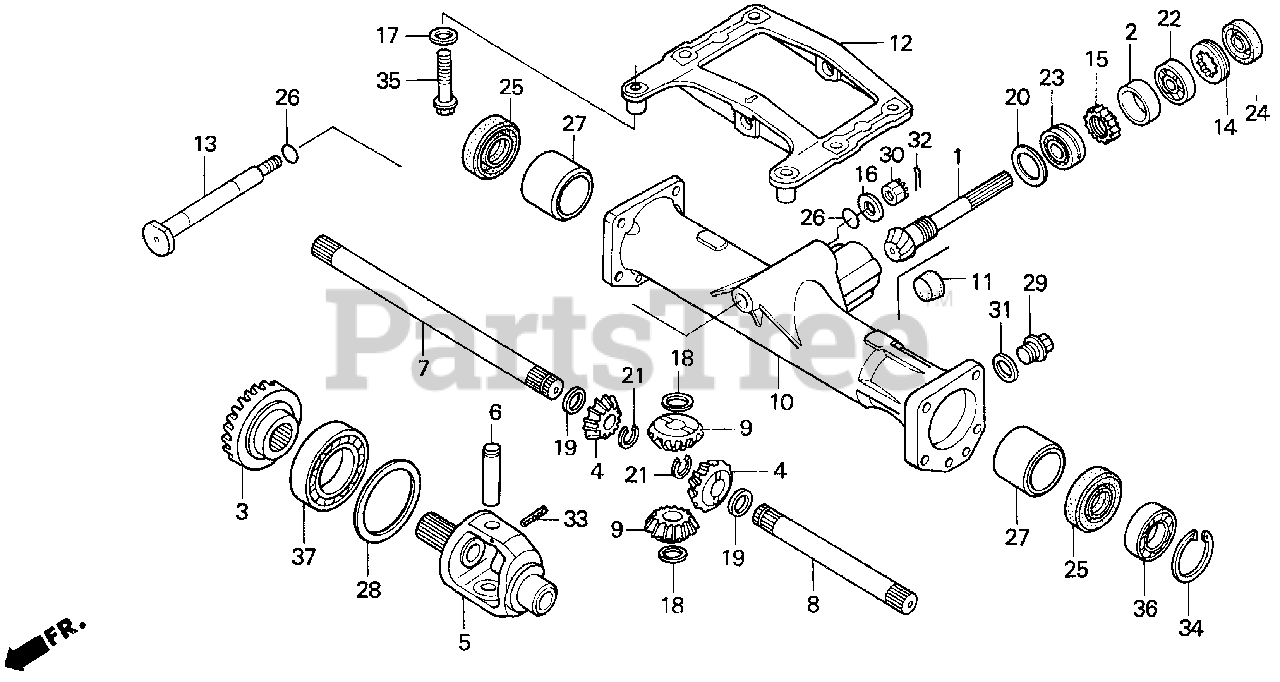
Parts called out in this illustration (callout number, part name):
1	SHAFT, FR. DIFFERENTIAL INPUT
2	COLLAR, FR. DIFFERENTIAL INPUT SHAFT
3	GEAR, FR. DIFFERENTIAL DRIVEN
4	GEAR, FR. DIFFERENTIAL SIDE
5	CASE, FR. DIFFERENTIAL GEAR
6	SHAFT, DIFFERENTIAL PINION
7	SHAFT, R. FR. DRIVE
8	SHAFT, L. FR. DRIVE
9	PINION, DIFFERENTIAL (14T)
10	TUBE, FR. AXLE
12	BRACKET, FR. AXLE
13	PIN, PIVOT CENTER
14	NUT, LOCK (55MM)
15	NUT, LOCK (25MM)
16	WASHER, PIVOT BOLT (NOT AVAILABLE)
17	WASHER, PLAIN (12MM)
18	WASHER A, DIFFERENTIAL PINION (16.2X30X0.7)
18	WASHER B, DIFFERENTIAL PINION (16.2X30X0.8)
18	WASHER C, DIFFERENTIAL PINION (16.2X30X0.9)
18	WASHER D, DIFFERENTIAL PINION (16.2X30X1.0)
19	WASHER, DIFFERENTIAL GEAR
20	SHIM, PINION (45.5X51.5X1.35) (A)
20	SHIM, PINION (45.5X51.5X1.4) (B)
20	SHIM, PINION (45.5X51.5X1.45) (C)
20	SHIM, PINION (45.5X51.5X1.5) (D)
20	SHIM, PINION (45.5X51.5X1.55) (E)
20	SHIM, PINION (45.5X51.5X1.6) (F)
20	SHIM, PINION (45.5X51.5X1.65) (G)
20	SHIM, PINION (45.5X51.5X1.7) (H)
20	SHIM, PINION (45.5X51.5X1.75) (I)
20	SHIM, PINION (45.5X51.5X1.8) (J)
20	SHIM, PINION (45.5X51.5X1.85) (K)
20	SHIM, PINION (45.5X51.5X1.9) (L)
20	SHIM, PINION (45.5X51.5X1.95) (M)
20	SHIM, PINION (45.5X51.5X2.0) (N)
20	SHIM, PINION (45.5X51.5X2.05) (O)
20	SHIM, PINION (45.5X51.5X2.1) (P)
20	SHIM, PINION (45.5X51.5X1.25) (R)
20	SHIM, PINION (45.5X51.5X1.3) (S)
21	CIRCLIP (OUTER) (20MM)
22	BEARING, SPECIAL (22) (KOYO)
23	BEARING, BALL (5205) (25X52X20.6)
24	OIL SEAL (22X58X10.5)
26	O-RING (21.8X2.4)
28	SHIM A, FR. DIFFERENTIAL (1.0)
28	SHIM B, FR. DIFFERENTIAL (1.05)
28	SHIM C, FR. DIFFERENTIAL (1.1)
28	SHIM D, FR. DIFFERENTIAL (1.15)
28	SHIM E, FR. DIFFERENTIAL (1.2)
28	SHIM F, FR. DIFFERENTIAL (1.25)
28	SHIM G, FR. DIFFERENTIAL (1.3)
28	SHIM H, FR. DIFFERENTIAL (1.35)
28	SHIM I, FR. DIFFERENTIAL (1.4)
28	SHIM J, FR. DIFFERENTIAL (1.45)
28	SHIM K, FR. DIFFERENTIAL (1.5)
28	SHIM L, FR. DIFFERENTIAL (1.55)
28	SHIM M, FR. DIFFERENTIAL (1.6)
28	SHIM N, FR. DIFFERENTIAL (1.65)
28	SHIM O, FR. DIFFERENTIAL (1.7)
28	SHIM P, FR. DIFFERENTIAL (1.75)
28	SHIM Q, FR. DIFFERENTIAL (1.8)
28	SHIM R, FR. DIFFERENTIAL (1.85)
28	SHIM S, FR. DIFFERENTIAL (1.9)
28	SHIM T, FR. DIFFERENTIAL (1.95)
28	SHIM U, FR. DIFFERENTIAL (2.0)
29	BOLT, DRAIN PLUG (20MM)
30	NUT, CASTLE (14MM)
31	WASHER, DRAIN PLUG (20MM)
32	PIN, COTTER (3.0X45)
33	PIN, SPRING (4X32)
34	CIRCLIP (INNER) (68MM)
35	BOLT, FLANGE (12X55)
36	BEARING, RADIAL BALL (6008)
37	BEARING, RADIAL BALL (6210)
